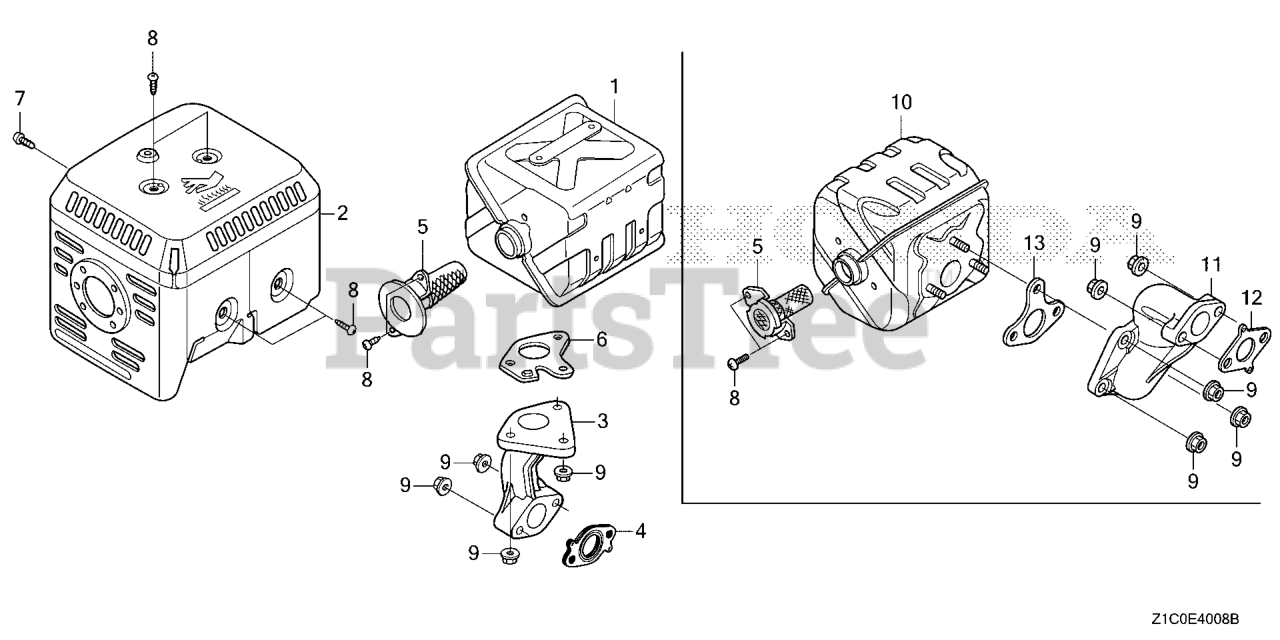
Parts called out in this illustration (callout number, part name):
1	MUFFLER
2	PROTECTOR, MUFFLER
4	GASKET, EX. PIPE
5	ARRESTER, SPARK
6	GASKET, MUFFLER (ARRESTER)
6	GASKET, MUFFLER (ARRESTER)(THAI LEAKLESS)
7	SCREW, TAPPING (6X10)
8	SCREW, TAPPING (5X8)
9	NUT, FLANGE (8MM)
